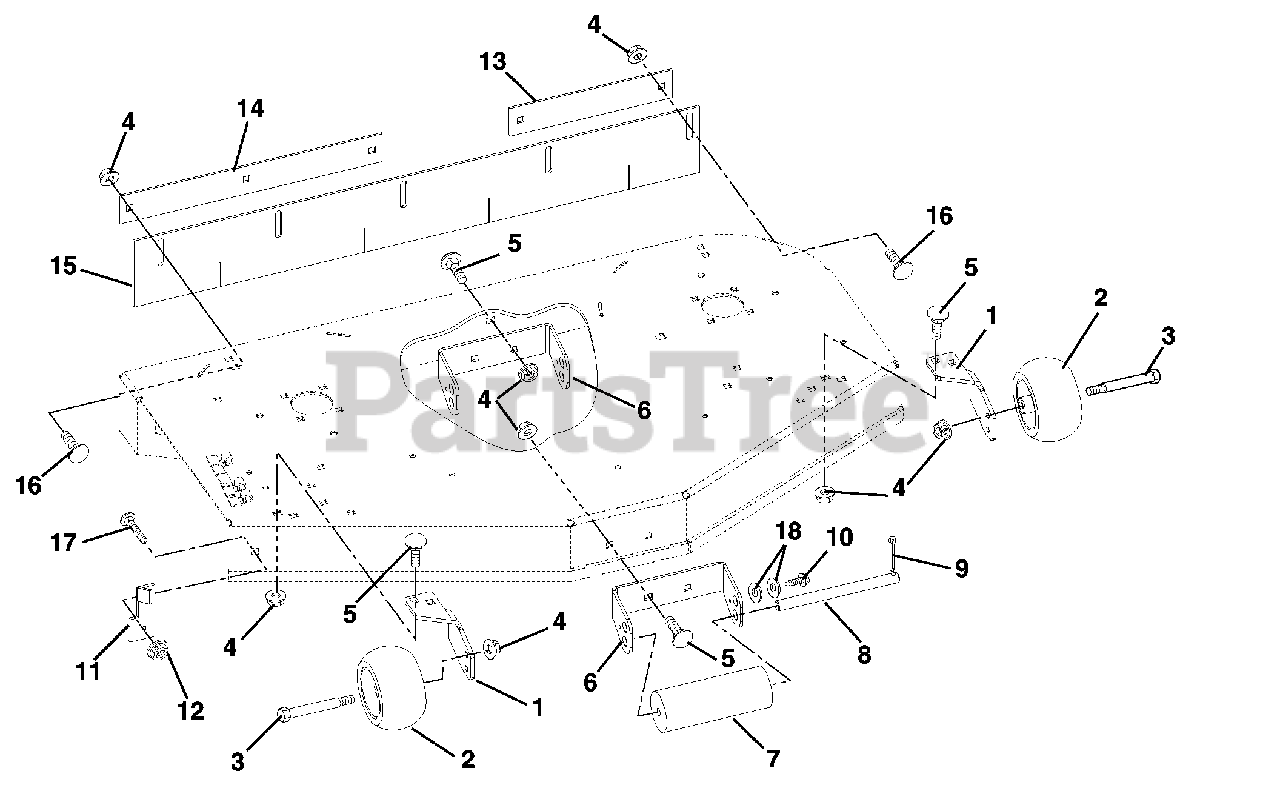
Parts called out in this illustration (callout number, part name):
1	BRACKET, ANTI SCALP
2	WHEEL 5 X 3
3	BLT-SHLDR .38-16X2.50 HWH G5
4	@NUT-LK-NYL-FLG .38-16 YWZC
5	@BLT-RDHDSQNK .38-16X1.00 G5YZ
6	BRACKET, ROLLER MOUNT
8	PIN, RETAINER
9	@PIN-CTR .25X1.00 YWZC
10	@SCR-TAP .25-20X.50 HWH TR YWZ
11	BRACKET, CHUTE LOCK
12	@NUT-SPNLK-FLG .375-16 YWZC
13	BAR, LH RETAINER STRIPER
14	BAR, RETAINING STRIPER-40"
14	BAR, RETAINING STRIPER-44"
15	BAR, RETAINING STRIPER-52"
15	STRIPER, RUBBER-40"
15	STRIPER, RUBBER-44"
15	STRIPER, RUBBER-48"
15	STRIPER, RUBBER-52"
16	@BLT-RDHDSQNK .38-16X1.00 G5YZ
17	@BLT-RDHDSQNK .38-16X1.25 G5YZ
18	@WSHR-FL-STL.344X.688X.065YWZC
